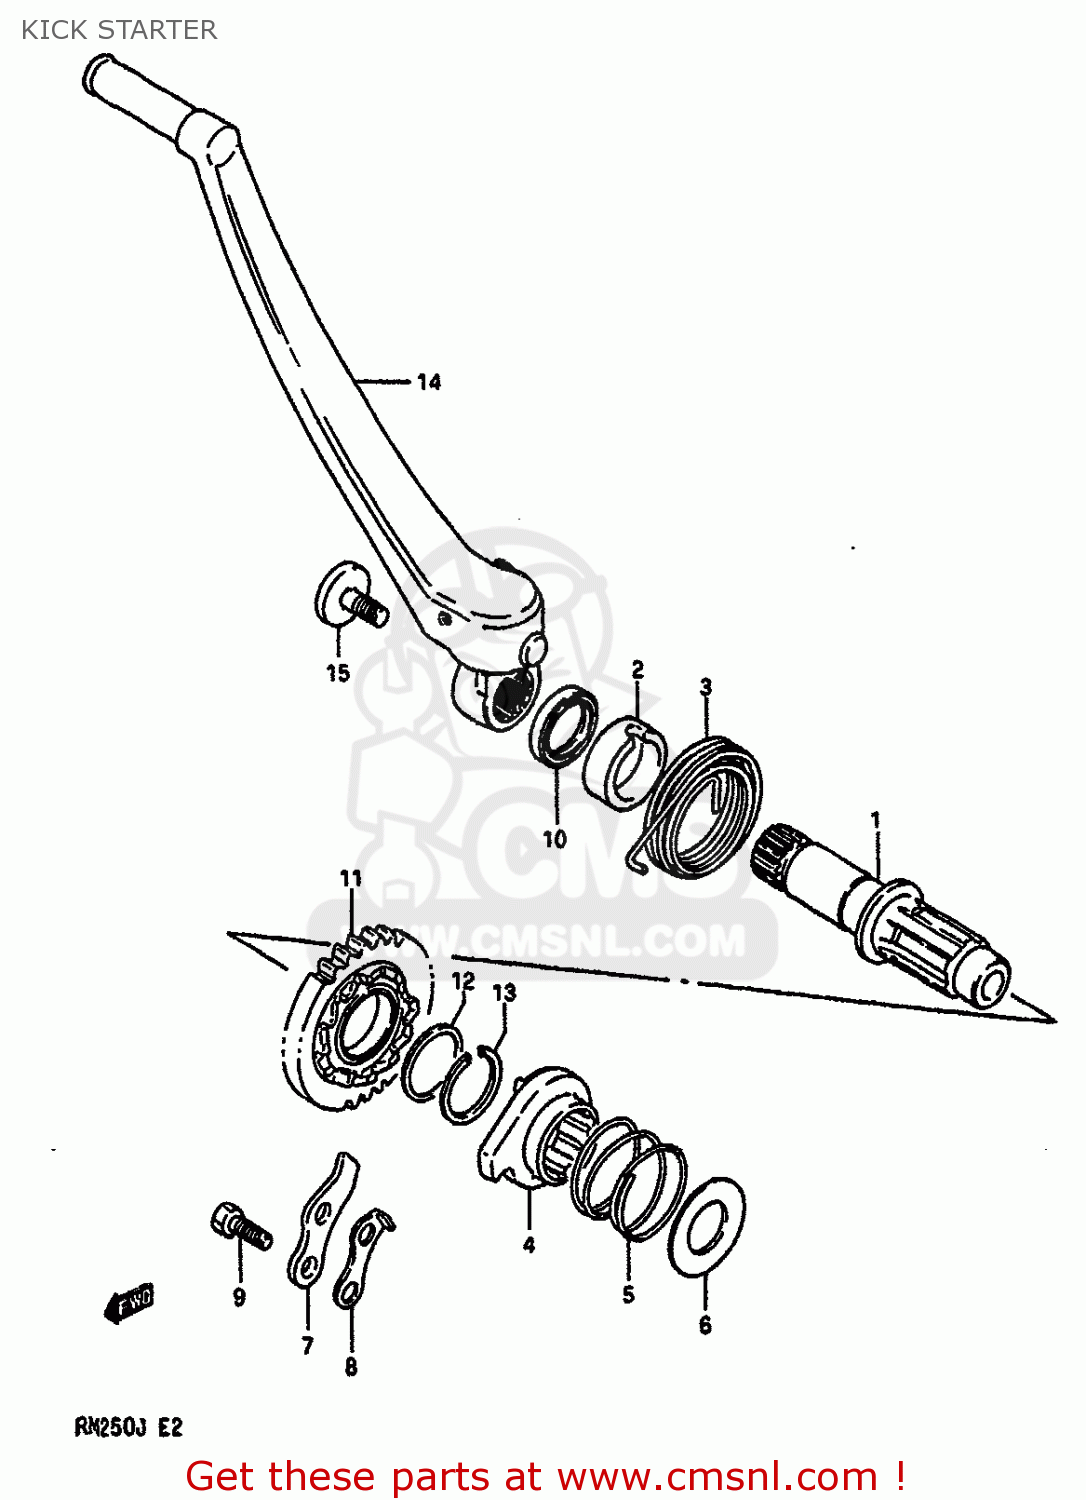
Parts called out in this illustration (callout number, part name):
1	SHAFT,KICK STARTER
2	GUIDE,KICK STARTER SHAFT
3	SPRING
4	STARTER,KICK
5	SPRING
6	WASHER
7	GUIDE,KICK STARTER
8	STOPPER,KICK STARTER
9	BOLT
10	SEAL,OIL(20X27X5)
11	GEAR
12	SHIM
13	CIRCLIP
14	LEVER ASSEMBLY,KICK STARTER
15	BOLT
